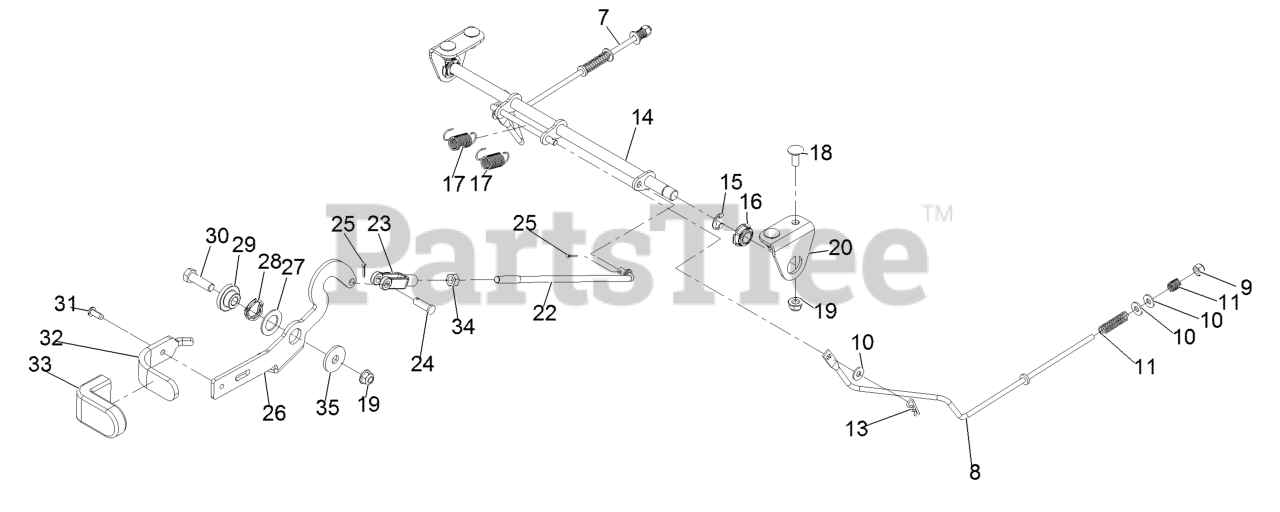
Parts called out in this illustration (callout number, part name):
7	ROD-BRAKE, WIDE (RH)
8	ROD-BRAKE, WIDE (LH)
9	NUT-LOCK, NI
11	SPRING-COMPRESSION
14	PIVOT-BRAKE
15	RING-RETAINING, EXTERNAL
16	BEARING-SPHERICAL
17	SPRING-EXTENSION
18	SCREW-CARR
19	NUT-HF, NI
20	ANGLE-MOUNT PIVOT
22	ROD-LINK HANDLE
23	YOKE-ADJUSTABLE
24	PIN-CLEVIS
25	PIN-COTTER
26	LEVER-BRAKE
27	WASHER-THRUST
28	WASHER-WAVE
29	PIVOT-FLANGE
30	SCREW-HH
32	HANDLE-BRAKE
33	GRIP-LEVER
34	NUT-HEX
35	WASHER
